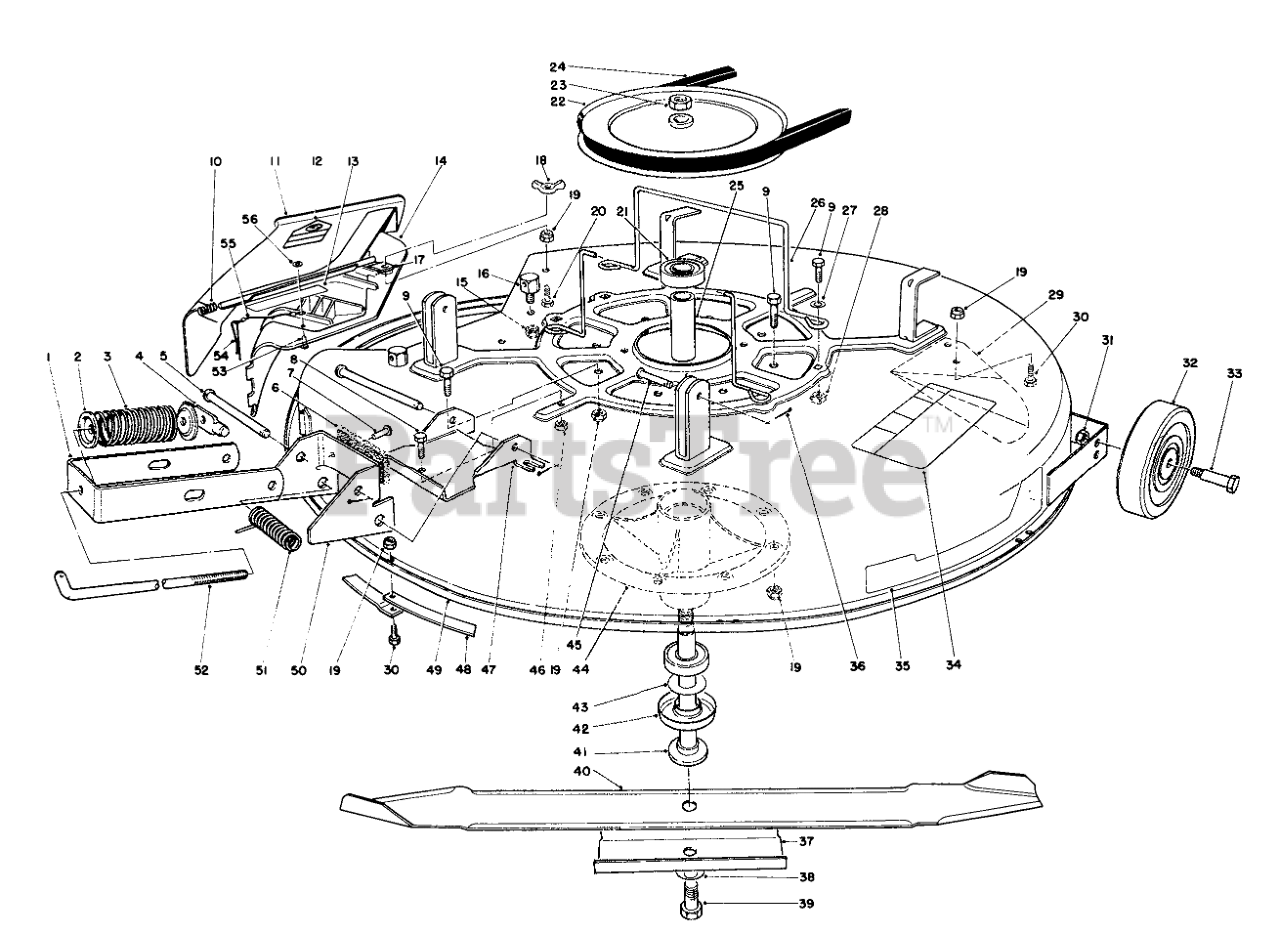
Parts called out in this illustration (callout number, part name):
1	Bracket-Engagement
2	RETAINER-SPR. TOP
3	SPRING-COMPRESSION
4	SHAFT-DECK ADJ.
5	PIN-CLEVIS
6	PAD-BRAKE
7	RIVET .187 X 7/16 BRASS
8	SCREW-HH
9	SCREW-HH
10	SPRING
11	Deflector (Incl. Ref. #12)
12	DECAL-DANGER
13	DECAL-DANGER, DEFLECTOR
14	Assy.-Cover, Discharge (Incl. Ref. #53-56)
15	NUT-LOCK, SIDE
16	POST-PIVOT
17	Brace-Cover, Rear
18	NUT-WING
19	NUT-LOCK, NI
20	SCREW-HH
21	BEARING-BALL
22	PULLEY
23	NUT-HEX
24	V-BELT, DECK
25	SPACER-BEARING
26	GUIDE-BELT
27	WASHER-PLAIN
28	NUT-RETAINER
29	Kicker
30	SCREW-HH
31	NUT-LOCK, NI
32	WHEEL-DECK
33	BOLT-WHEEL
34	DECAL-DANGER, THROWN OBJECT
35	DECAL/RECYCLER 32" BACK
36	PIN-COTTER
37	STIFFENER
38	WASHER-BELLEVILLE
39	SCREW-HH
40	BLADE-RECYCLER
41	SHAFT-SPINDLE
42	SHIELD-BEARING
43	SPACER-HARDNED
44	SPINDLE
45	PIN-CLEVIS
46	NUT-HEX
47	Plate-Deck, Brake Mtg.
48	RING-DECK
49	Deck-Cutting
50	Brake (Incl. Ref. #6-7)
51	SPRING
52	ROD-ENGAGEMENT
53	RIVET-BLIND
54	PIN-LOCKING, CHUTE
55	LANYARD
56	WASHER-PLAIN
